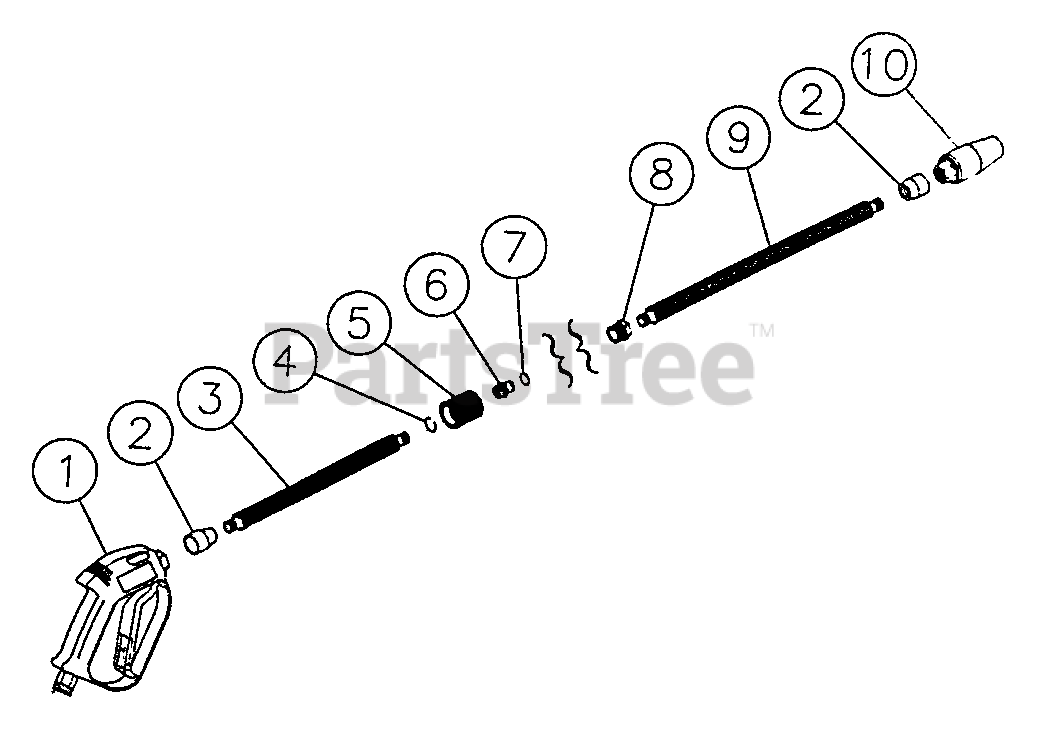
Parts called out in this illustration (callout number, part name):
1	Gun Assembly
2	Protective Cover
3	Insulated Lance
4	Retaining Ring
5	Hand Wheel
6	Plug/Screw Connect
9	Insulated Lance
10	Variable Nozzle (1.2mm)
